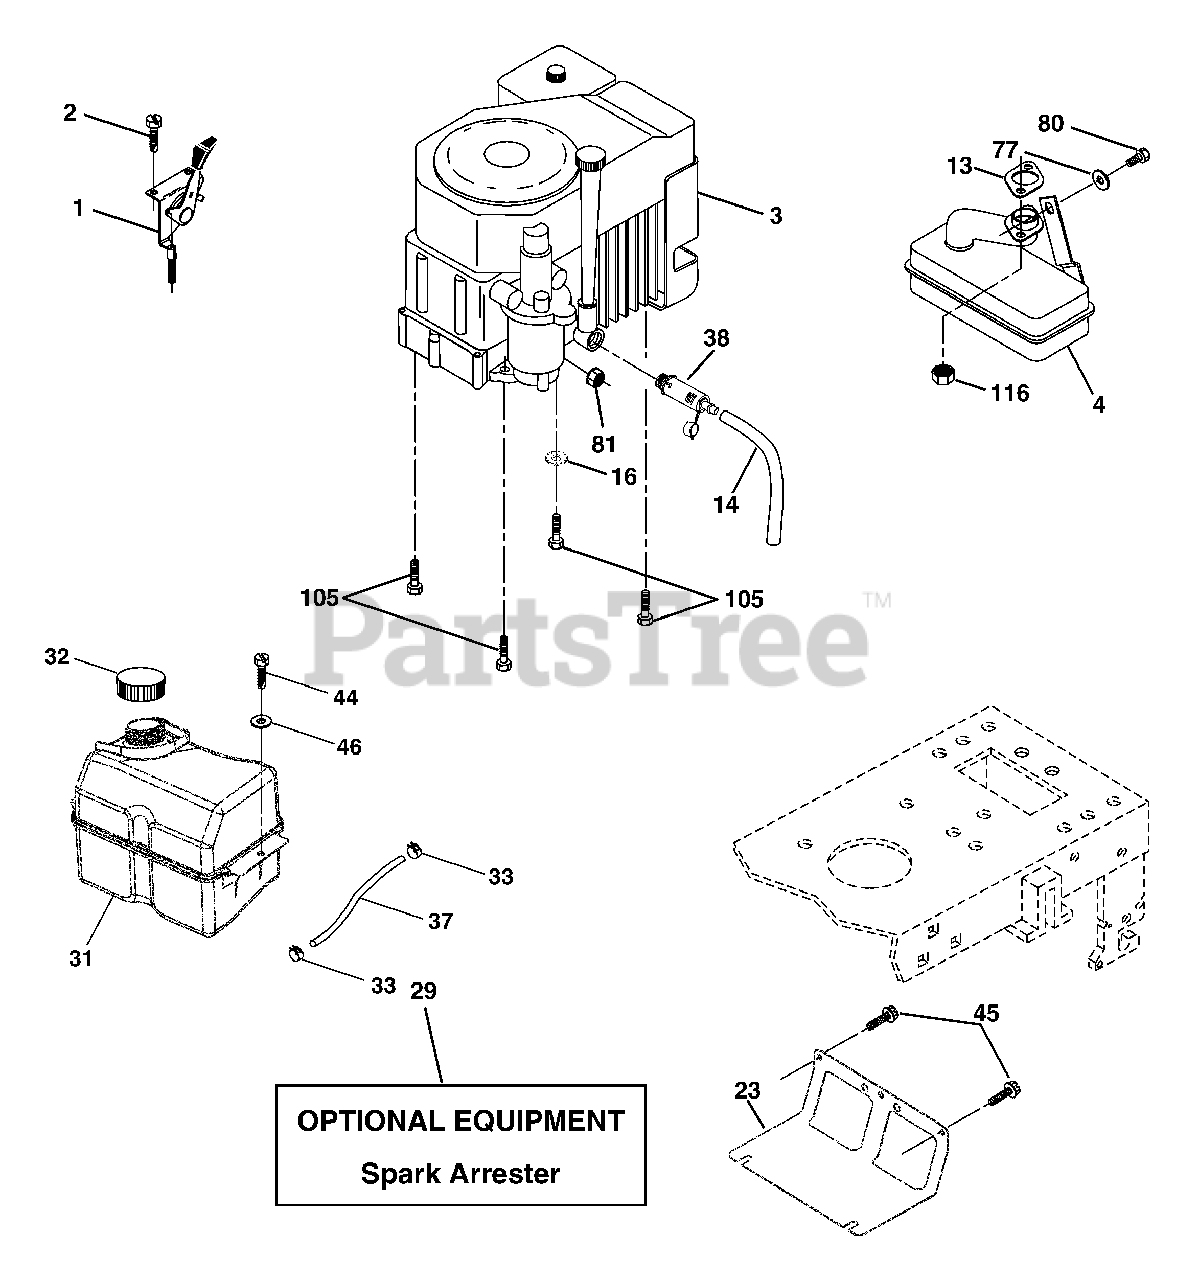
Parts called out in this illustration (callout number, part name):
1	Control Throt/Ch Flag
2	Screw Hex Thd Cut 1/4-20 x 1/2
4	Muffler Exhaust
14	Tube Drain Oil Easy
16	Washer Lock Ext Tooth 3/8
23	Shield Browning/Debris Guard
29	Arrestor Spark
31	Tank Fuel
32	Cap Asm Fuel W/sym Vented
33	Clamp Hose Blk
37	Line Fuel 20"
38	Plug Drain Oil Easy
44	Screw Hexwsh Thdrol 1/4-20 x 3/4
45	Screw Hex Wsh Thdrol 3/8-16
46	Washer 9/32 x 7/8 x 16ga
77	Washer 5/16 x 3/4 x 16 Ga.
80	Bolt Hex Hd 5/16-18 Unc x 1/2
81	Nut Keps Hex 1/4-20 Unc
105	Screw 3/8-16 x 1
116	Nut Hex Flange Toplock M8-1.25
